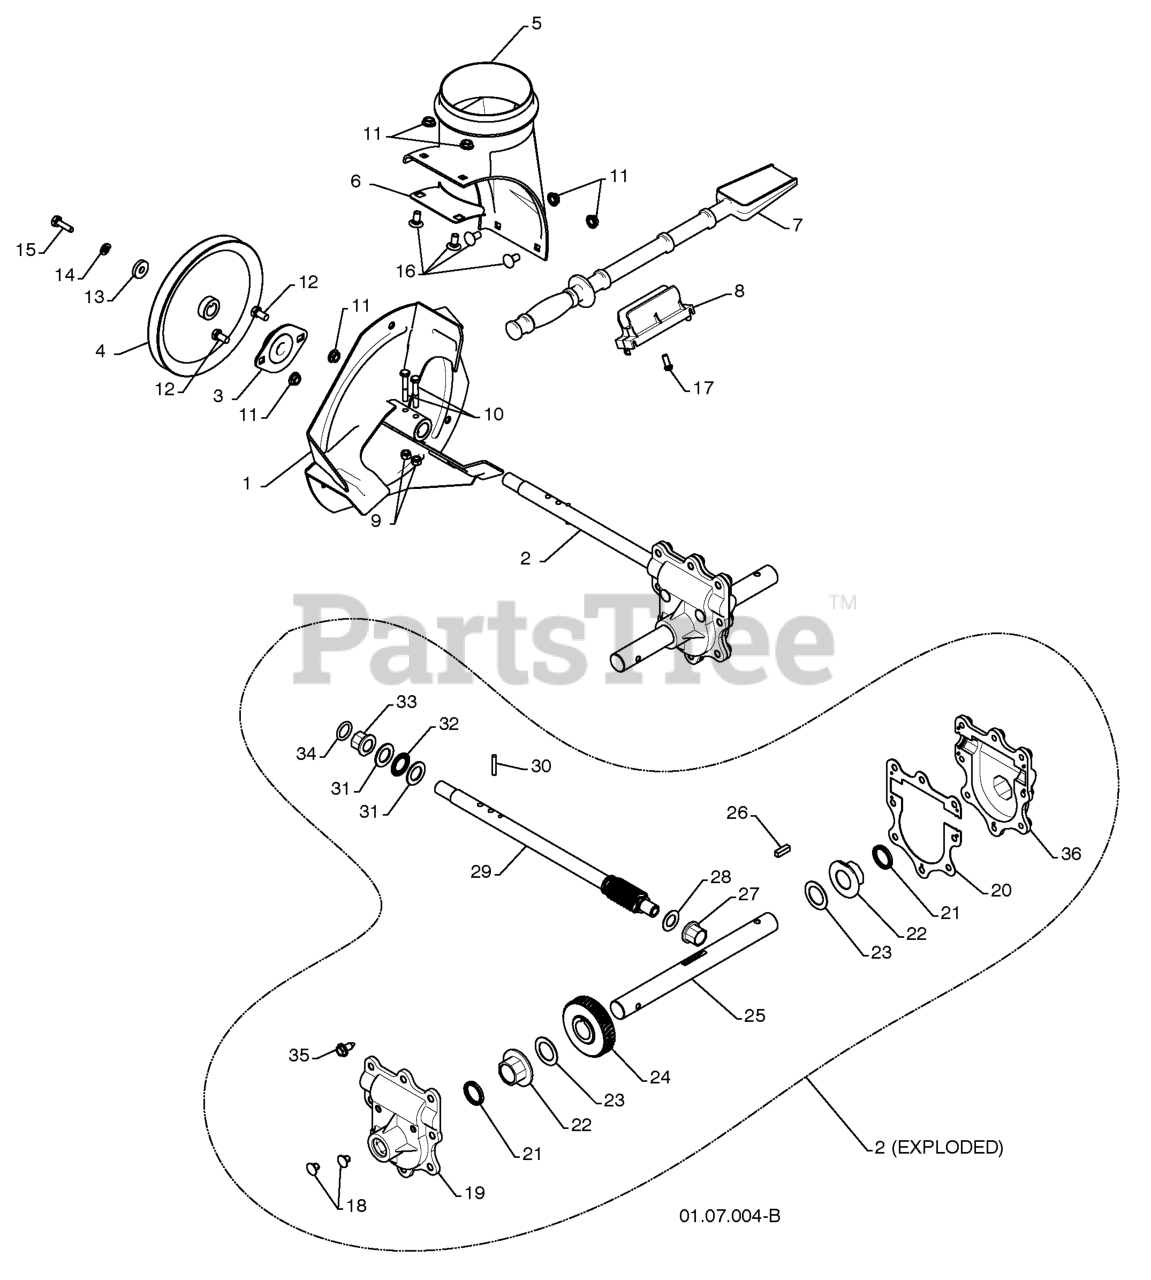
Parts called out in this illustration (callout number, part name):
1	PLASTIC RETAINER
2	AUGER BALL BEARING
3	SCREW 5/16-18 X 1.00
